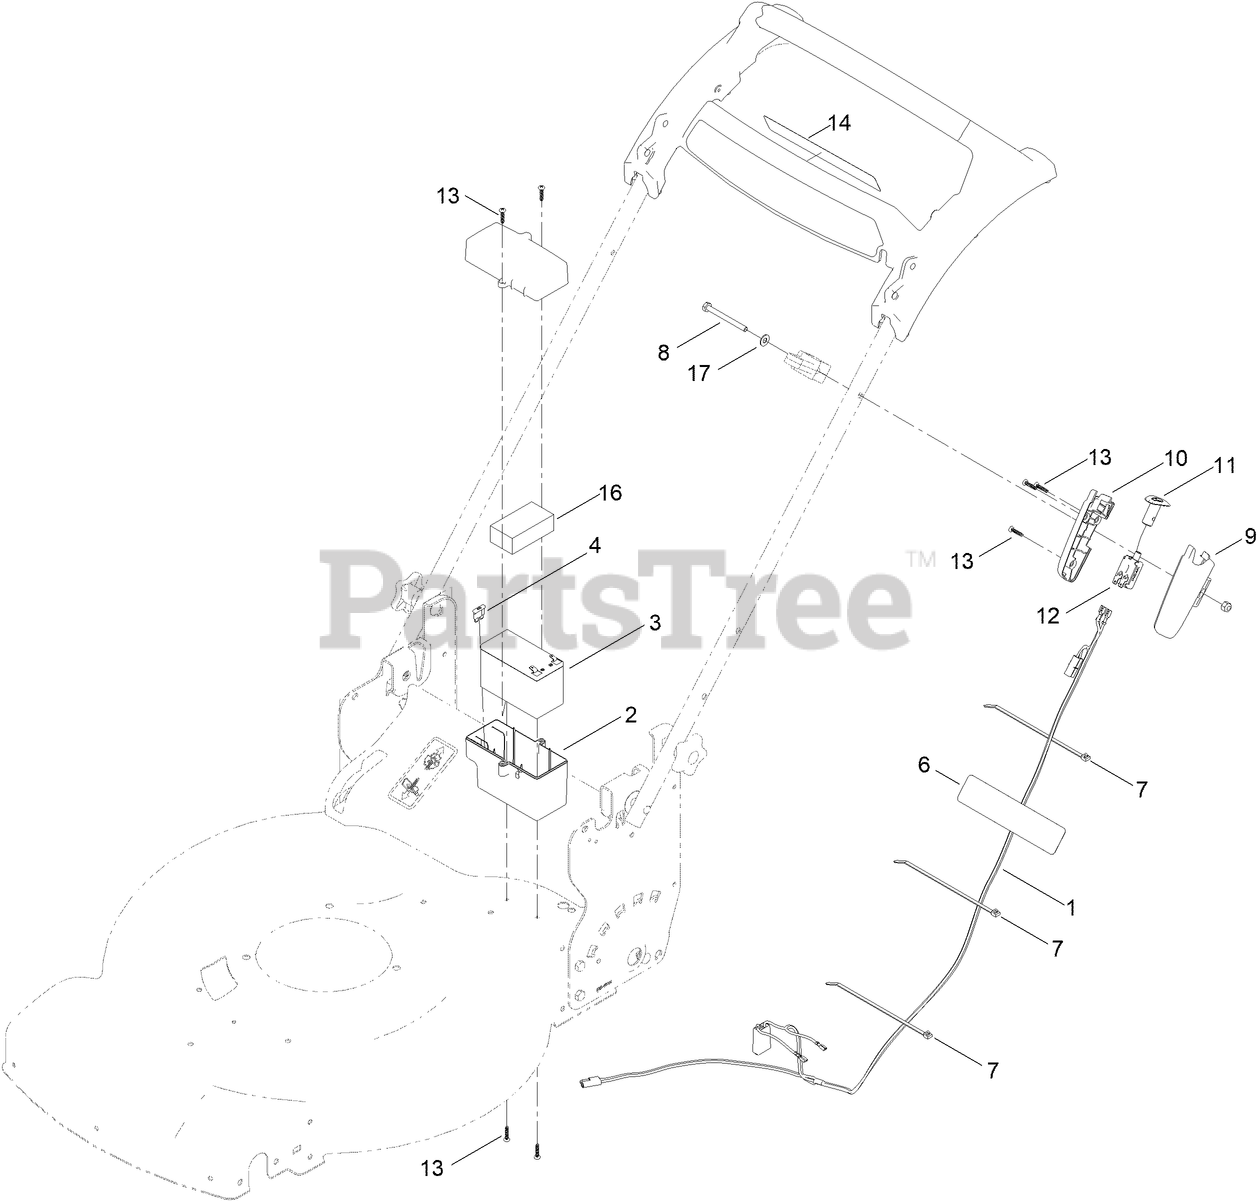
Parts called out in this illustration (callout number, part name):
1	HARNESS-WIRE
2	BATTERY BOX ASM
3	BATTERY-NONSPILLABLE, 12 V
4	FUSE-40 AMP
6	DECAL-BATTERY CHARGING
7	TIE-CABLE
8	SCREW-HH
9	HOUSING-SWITCH, LH
10	HOUSING-SWITCH, RH
11	BUTTON-SWITCH
12	SWITCH-PUSH BUTTON
13	SCREW-PPH
14	DECAL-BUTTON, PUSH
16	FOAM-BATTERY, TOP
17	WASHER-FLAT
